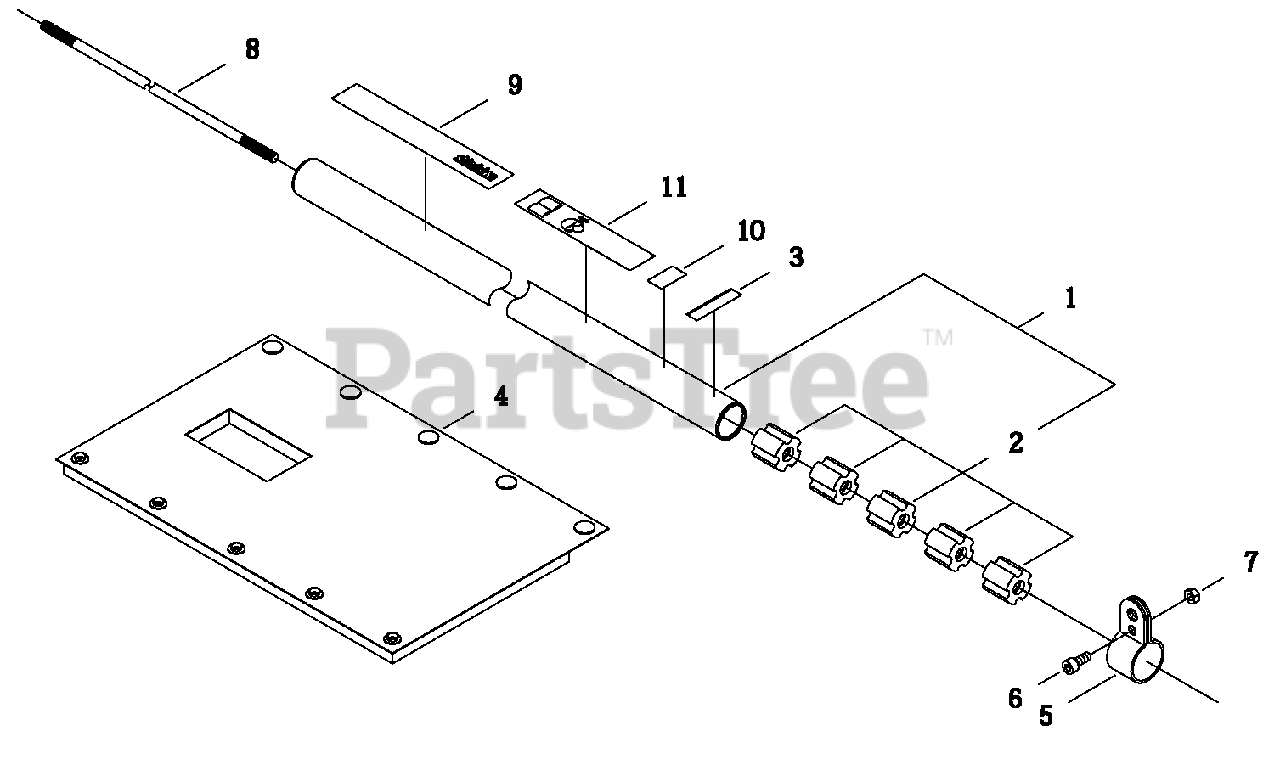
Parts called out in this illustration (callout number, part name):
1	MAIN PIPE ASSY
2	BUSHING
3	LABEL - ALIGNMENT
4	SLEEVE, PROTECTOR
5	BRACKET
6	SCREW - 5X12
7	NUT - 5
8	DRIVESHAFT - SOLID
9	LABEL - SHINDAIWA PROFESSIONAL
10	LABEL - HANDLE LOCATION
11	LABEL - CAUTION
